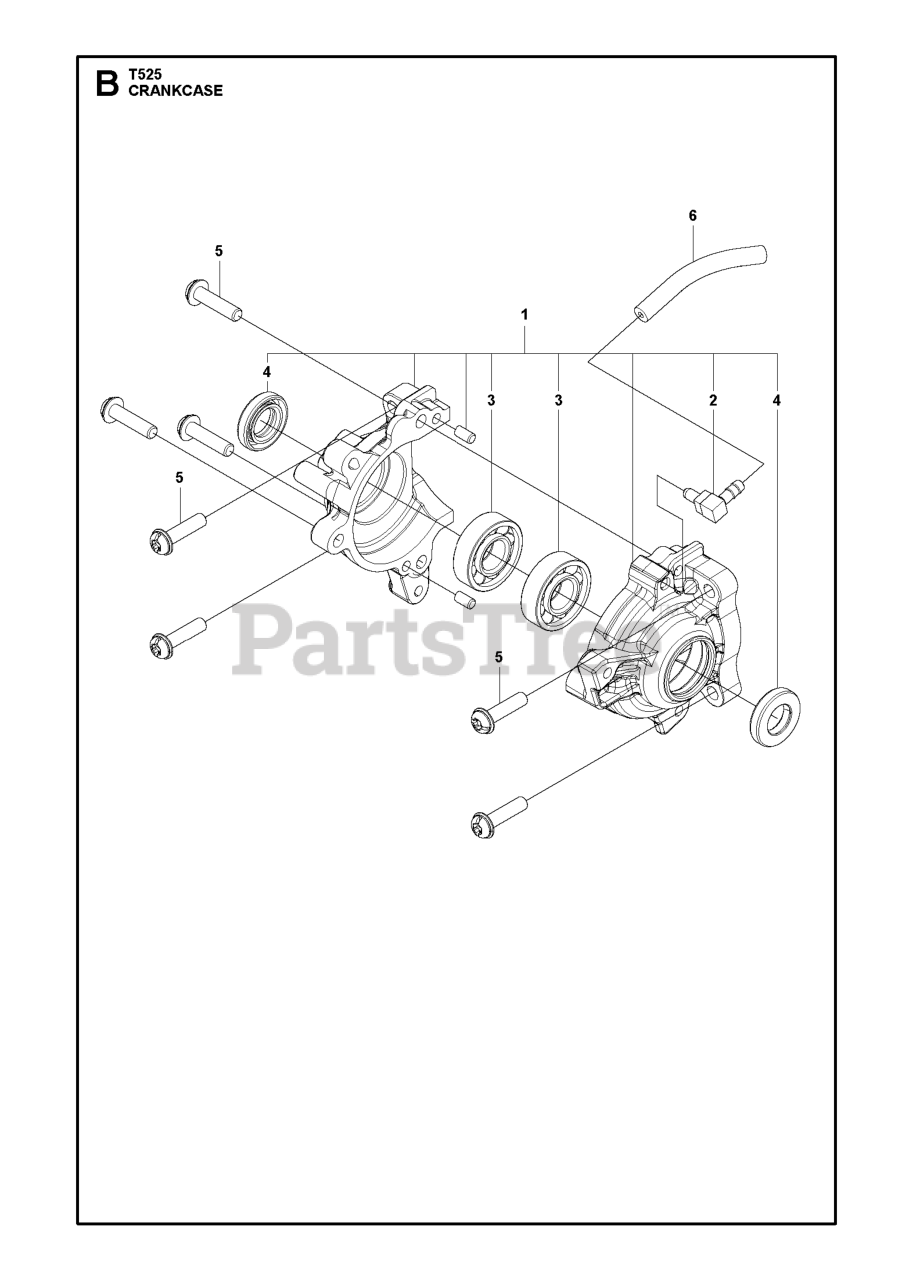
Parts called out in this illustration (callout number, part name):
1	CRANKCASE ASSY
2	ELBOW FITTING
3	BALL BEARING 7MM
4	OIL SEAL(RPLS 284121210)
5	SCREW HEXABOULAR SLOTTED SOCKE
6	IMPULSE HOSE
